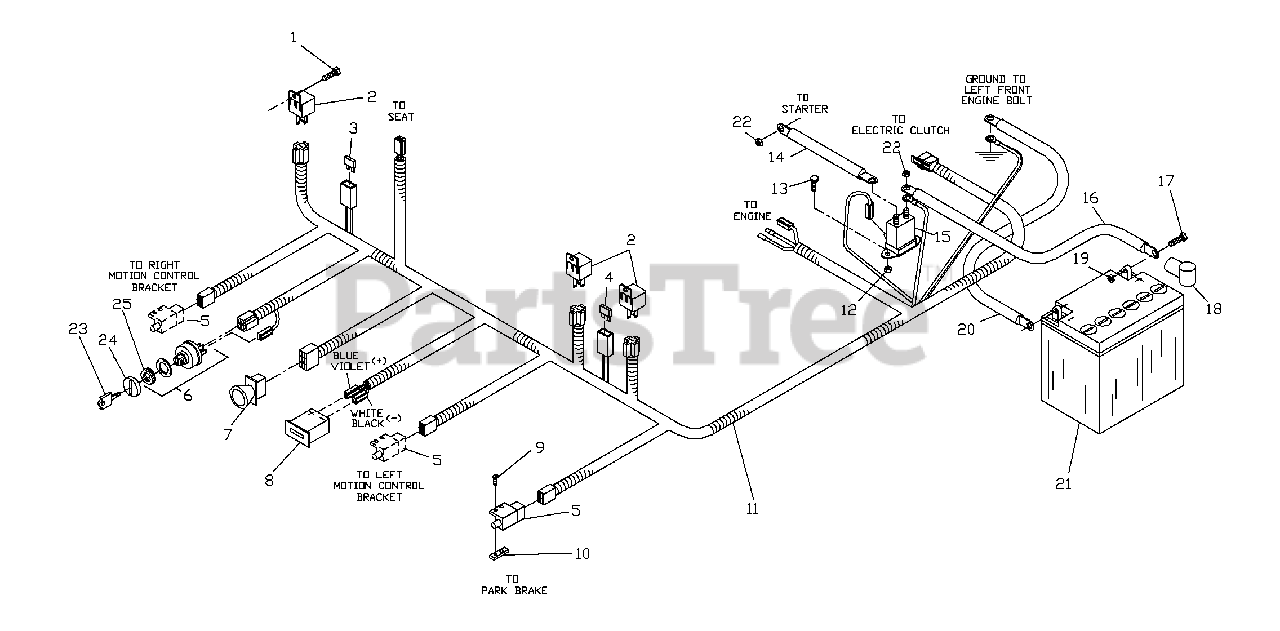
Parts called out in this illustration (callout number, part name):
1	#10 X 1/2 SELF TAPPING
3	7.5 AMP 32 VOLT ATO FUSE
4	20 AMP 32 VOLT ATO FUSE
5	INTERLOCK SWITCH
6	IGNITION SWITCH
7	BLADE SWITCH
8	HOUR METER
9	#10-24 X 5/8
10	TAPPED PLATE
11	WIRING HARNESS
12	NUT 1/4C CENTERLOCK
13	HCS 1/4C X 5/8
14	CABLE POSITIVE
16	CABLE POSITIVE, LONG
17	HCS 5/16C X 3/4
19	NUT 5/16C CENTERLOCK
20	CABLE NEG.
21	BATTERY
22	NUT 1/4C NYLOC
23	KEY, PADDED
